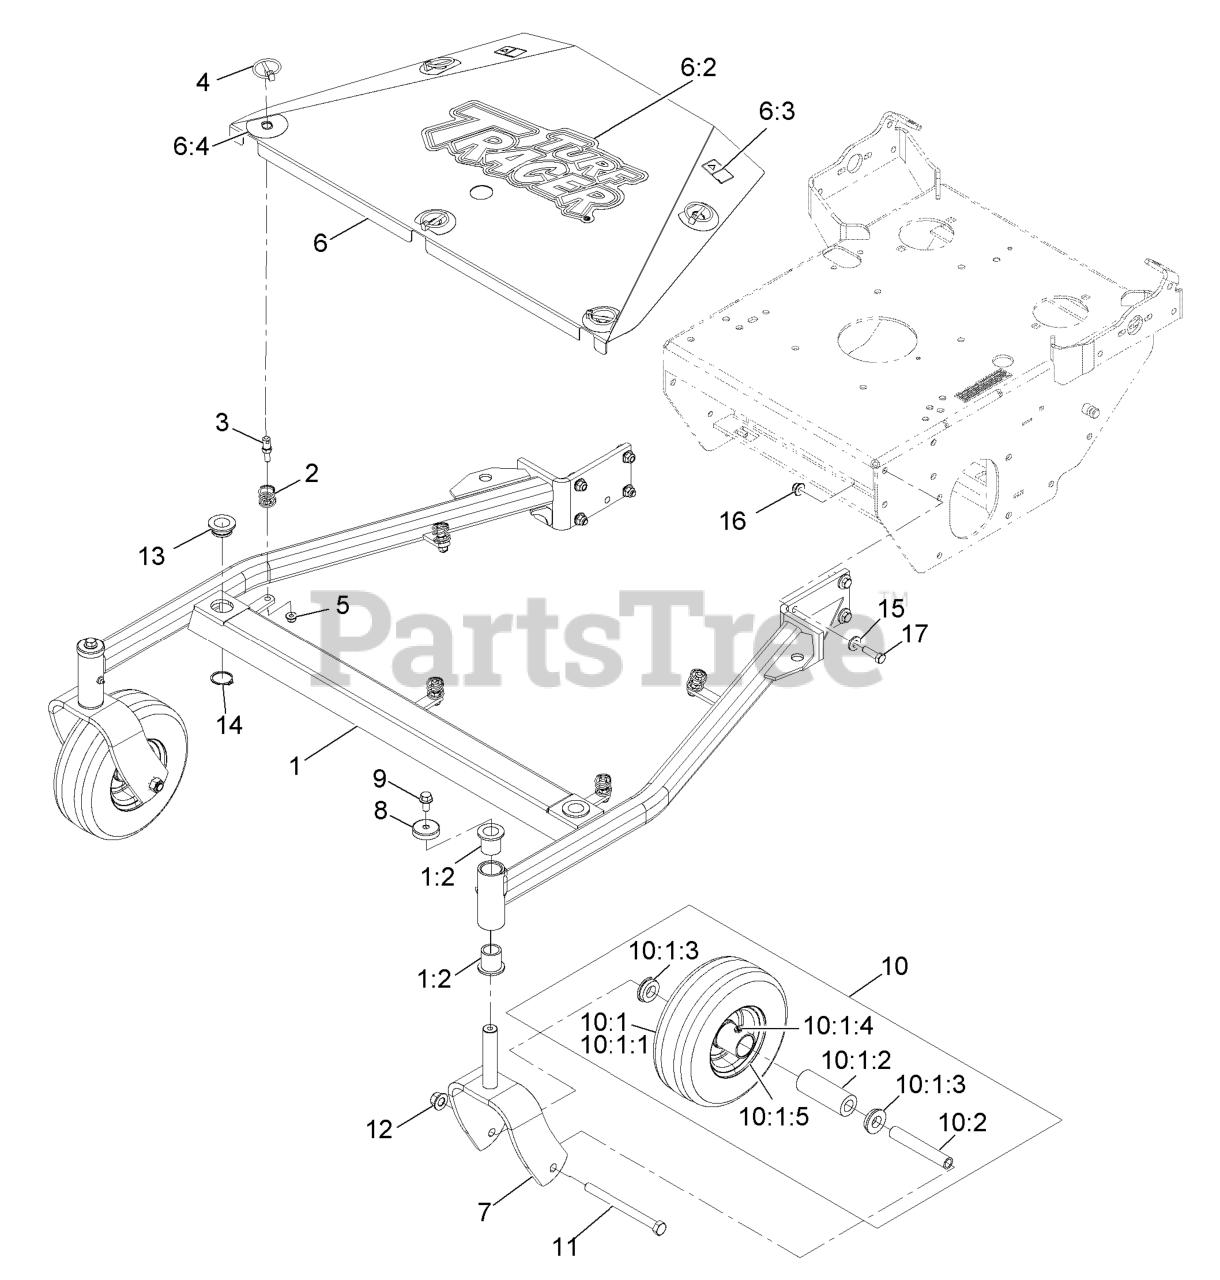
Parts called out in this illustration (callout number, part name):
1	ASM, FRAME W/ BUSHINGS, 3
1:2	BEARING-FLANGED
3	PIN-SPRING
4	PIN-LYNCH
5	NUT-HF, NI
6	ASM, SHIELD W/ DECALS, 36
6:2	DECAL,TTH MODEL
6:3	DECAL-WARNING
6:4	DECAL-SCRATCH COVER
7	FORK, CASTER
8	CAP, DUST
9	SCREW-HHF
10	KIT, SP CASTER WHEEL REPL
10:1	Wheel And Tire ASM
10:1:1	Tire
10:1:2	BEARING
10:1:3	BUSHING
10:1:4	FITTING-GREASE
10:1:5	Wheel
11	SCREW-HH
12	Nut-Lock 1/2-13
13	BUSHING-DECK
14	RING-RETAINING
15	WASHER-BELLEVILLE
16	NUT-HF, NI
17	SCREW-HH
